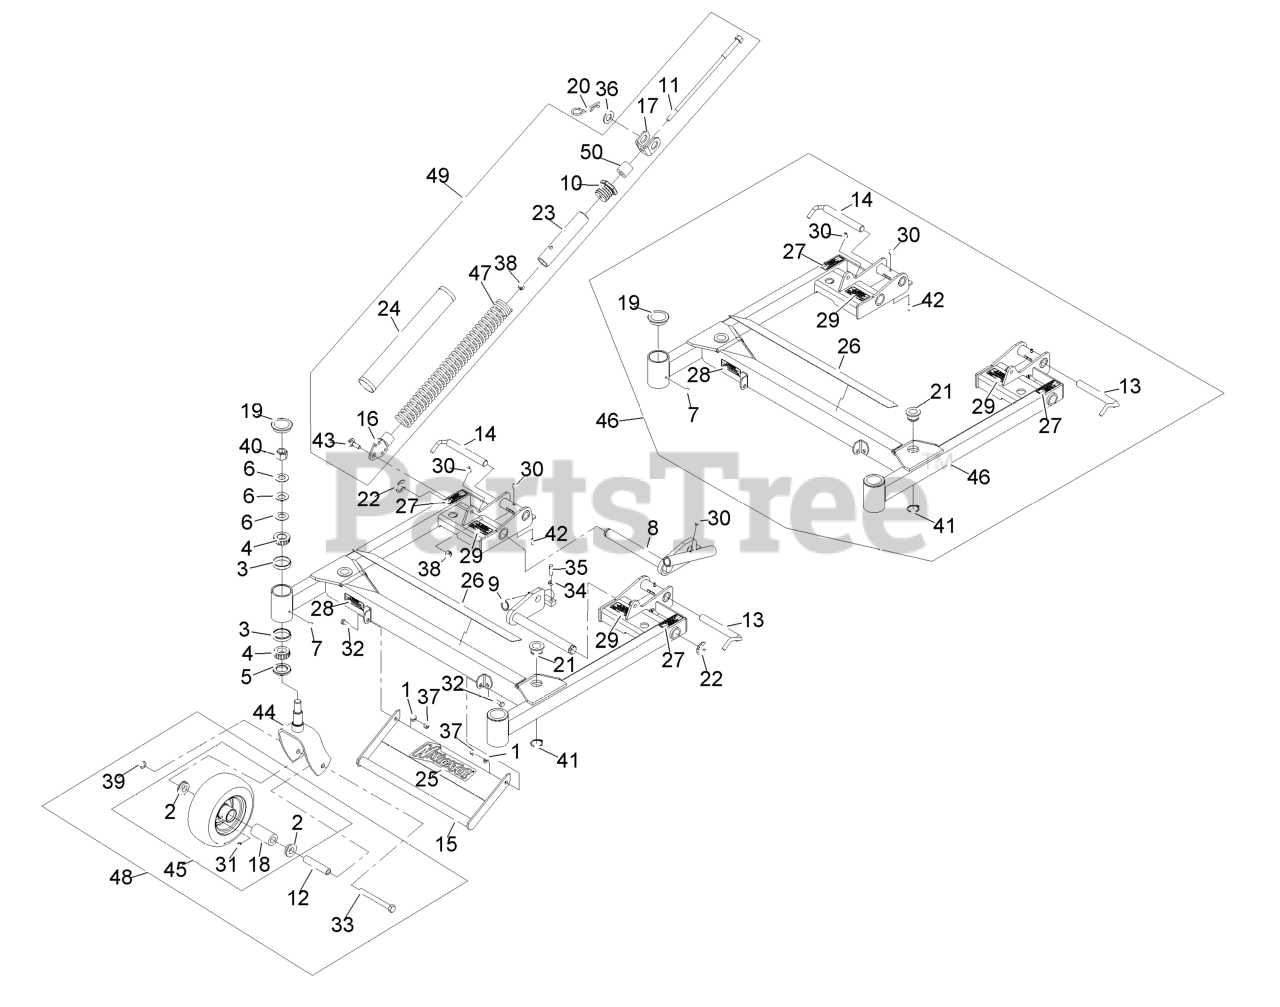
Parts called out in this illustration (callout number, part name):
1	WASHER-SPRING
2	BUSHING
3	CUP-BEARING
4	Cone-Bearing Tapered Roller
5	SEAL-GREASE
6	WASHER-BELLVILLE
8	PIVOT-DECK, RH
9	PIVOT-DECK, LH
10	PLUG-ADJUSTER, SPRING
11	SHAFT-ADJUSTMENT, SPRING
12	SPACER-CASTER, FRONT
13	LOCK-DECK, LH
14	LOCK-DECK, RH
15	ASM,DECK LIFT HANDLE W/DE
16	TENSIONER-SPRING
17	MOUNT-LIFT ASSIST, DECK
18	BEARING-ROLLER, STRAIGHT
19	CAP-GREASE
20	PIN-CUT HEIGHT
21	BUSHING-SUPPORT, DECK
22	RING-SNAP
23	SPRING-TUBE
24	COVER-SPRING, DECK
25	DECAL,NAVIGATOR MODEL
26	PAD-SKID, ANTI
27	DECAL-FOLDING DECK
28	DECAL-DANGER
29	DECAL-SPRING
30	FITTING-GREASE
31	FITTING-GREASE
32	SCREW-HH
33	SCREW-HH
34	NUT-JAM
35	SCREW-SET, SQH
36	WASHER-FLAT
37	NUT-LOCK, NI
38	NUT-LOCK, NI
39	NUT-HEX
40	NUT-LOCK, NI
41	RING-RETAINING
42	PIN-SPRING
43	SCREW-SHOULDER, HWH
44	FORK-CASTER
45	ASM,WHEEL,TIRE & BRGS 8X3
46	DECK SUPPORT ASM
47	SPRING-EXTENSION
48	ASM,FF CASTER WHEEL W/AXL
49	ASM,LIFT AST SPRING
50	SPACER (PLATED)
